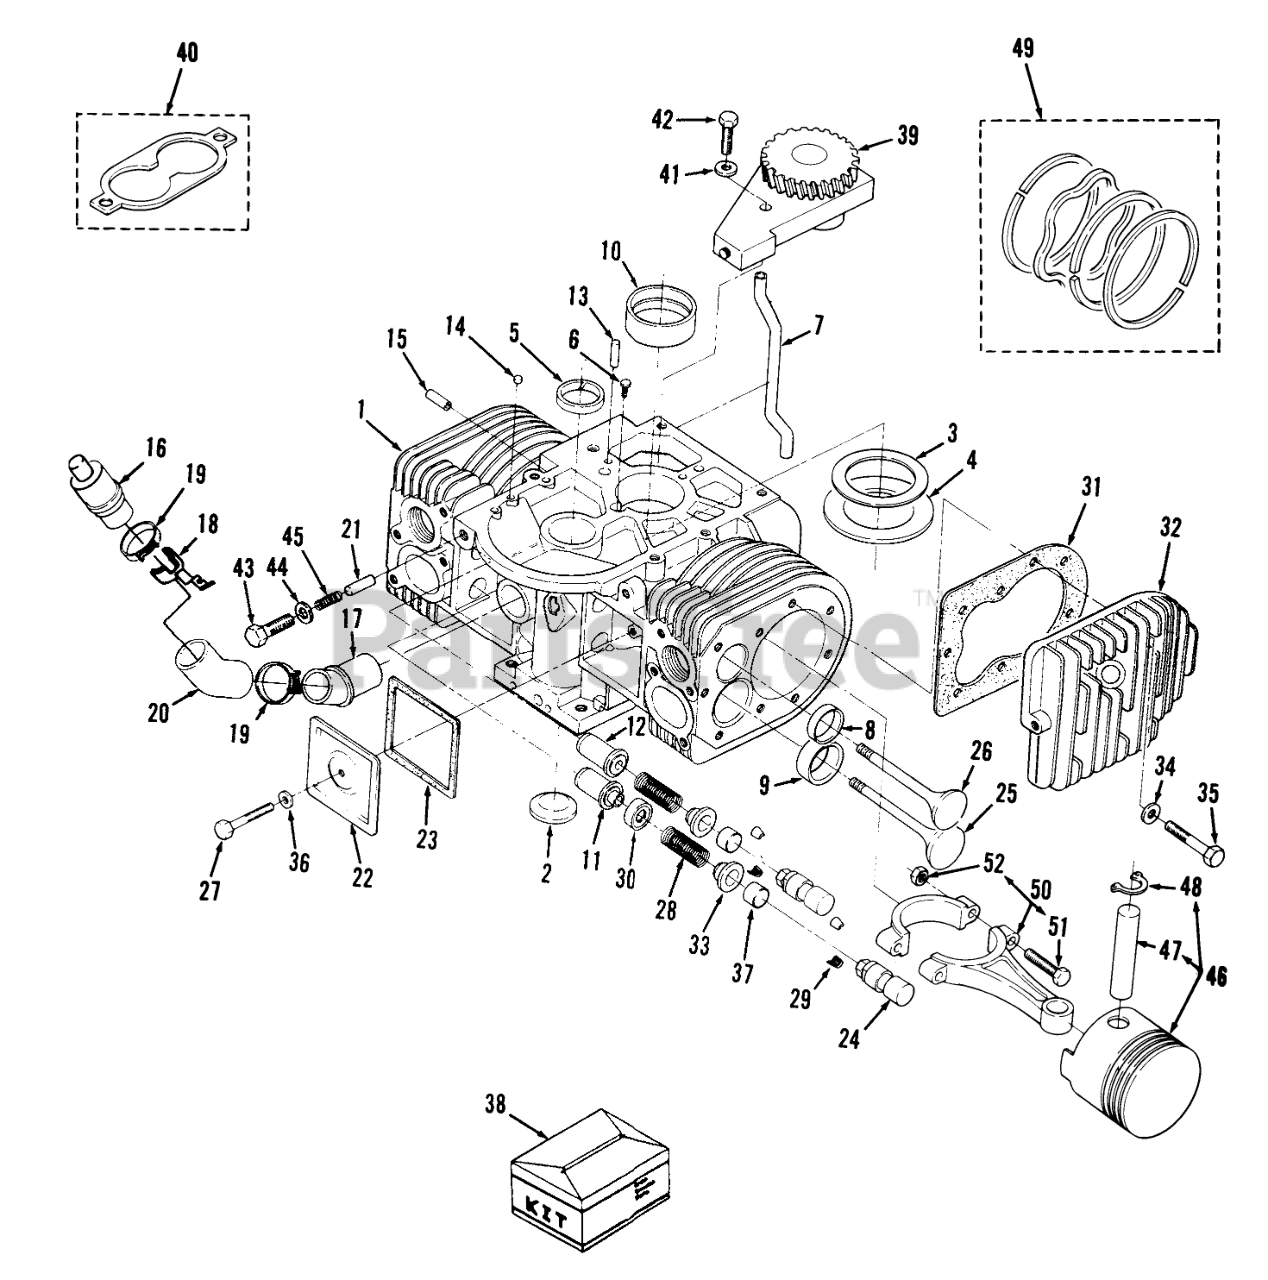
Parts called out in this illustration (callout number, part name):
1	BLOCK-ASS'Y CYLINDER
2	Plug
3	PISTON
4	WASHER
5	SLEEVE-BEARING
6	Screw
7	OIL TUBE
8	Standard
9	SEAT-INT VALVE (STD)
10	KIT-BEARING, SLEEVE
11	Guide-Intake Valve
12	Guide-ExhaustValve
13	Pin
14	PLUG-CORE HOLE
15	TUBE-PORT, VACUUM
16	Breather Tube
17	BREATHER-ADAPTER
18	BREATHER-MTG BRKT
19	Hose Clamp
20	BREATHER-HOSE
21	DOWEL-PIN PLUG
22	Cover-Valve
23	Gasket
24	TAPPET
25	Intake Valve
26	Exhaust Valve
27	HHCS 1/4-20 X 1 3/4
28	Spring
29	VALVE SPRING LOCK
30	Seal
31	GASKET
32	Side-Left
33	Washer
34	WASHER
35	Bolt
36	WASHER
37	Cap-Valve
38	KIT - GASKET
39	OIL-PUMP
40	GASKET KIT
41	Washer
42	Bolt
43	SCREW-HH
44	WASHER
45	SPRING
46	Standard
47	Pin-Piston
48	Piston Pin
49	RING SET
50	Rod w/Bolts & Nuts-Standard-616-Z
